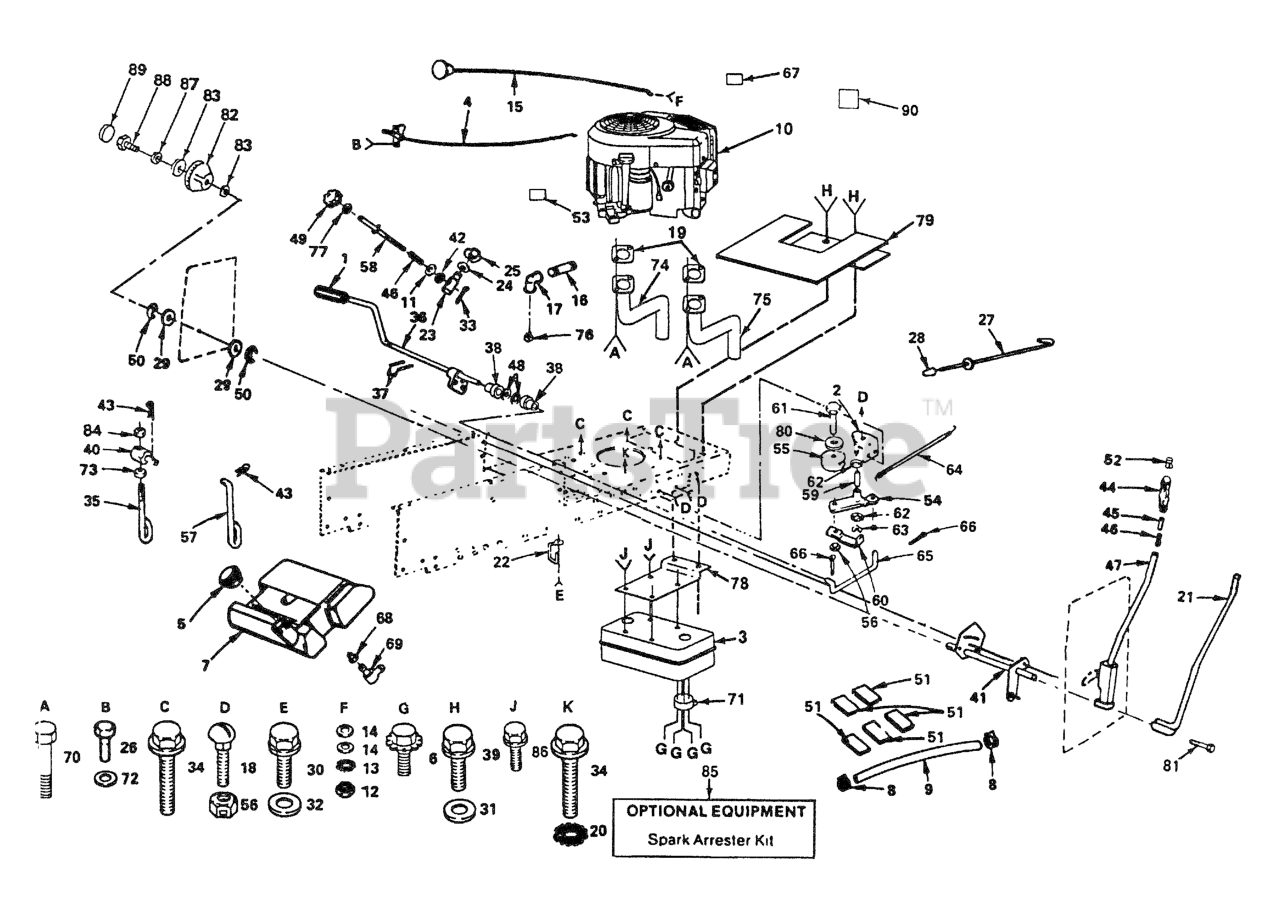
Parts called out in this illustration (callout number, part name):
1	PEDAL COVER T
4	CONTROL THROTTLE
5	FUEL CAP ASS'Y
6	Screw-Spider Lock
7	FUEL TANK LT
8	HOSE CLAMP
9	FUEL LINE 42"
10	DEFL MUFFLER LTV
12	NUT
13	LOCKWASHER
14	WASHER
15	CONTROL CHOKE
16	Std. Pipe Nipple
17	ELBOW
18	Bolt-Carr. 3/8-16 x 3/4
19	Gasket, Muffler
20	LOCKWASHER
21	LEVER ROD LT
22	BELT RETAINER
23	TRUNION LT
24	Washer 15/32 x 3/4 x 16 Ga.
26	Screw-Hex Washer Hd. Thd. Cutting 1/4-20 x 1/2
27	ROD BRAKE PARK
28	PLUNGER CAP
29	Washer 29132 x 1-1/4 x 16 Ga.
30	SCREW
31	WASHER
32	WASHER
33	COTTER PIN
34	SCREW LT
35	LINK ADJ T
36	SHAFT FOOT PEDAL
37	PIN.ROLL.3/16 X 1"
38	BEARING.NYLON
39	SCREW.THDROL.5/16-18X3/4.TTY
40	TRUNNION T
41	SHAFT LIFT
42	NUT T
43	RETAINER-SPRNG RB
45	PLUNGER BUT KIT
46	SPRING**
47	LIFT LEVER KIT
48	WASHER LT
49	HDLE ADJ LIFT
51	PAD-SPACER T
52	PLUNGER BUT KIT
53	DECAL,MAINTENANCE
55	IDLER PULLEY
57	LIFT LINK LT
58	ROD LIFT LT
59	BEARING LT (2 2)
60	RETAIN BELT
61	Bolt-Hex 3/8-16 x 1-1/2
64	SPRING, RETURN LT
65	LINK, CLUTCH LT
66	COTTER PIN
67	DECAL ENGINE
68	BUSHING OUTLET T
69	FUEL TANK STEM GT
70	Bolt, Metric
71	DEFL MUFFLER LTV
72	WASHER LT
73	NUT **
74	TUBE ASSY EXH LH
75	TUBE ASSY EXH RH
77	NUT
78	BRACKET MUFFLER
79	HEAT SHIELD
80	WASHER
81	BOLT
82	HEIGHT INDICATOR
84	NUT LOCK YTH
85	SPARK ARR MUFF GT
86	SCREW
87	WASHER.LOCK.HVY.HLCL.SPR.5/16
88	BOLT.FIN.HEX.5/16-18UNC X 1.00
90	DECAL ENGINE
